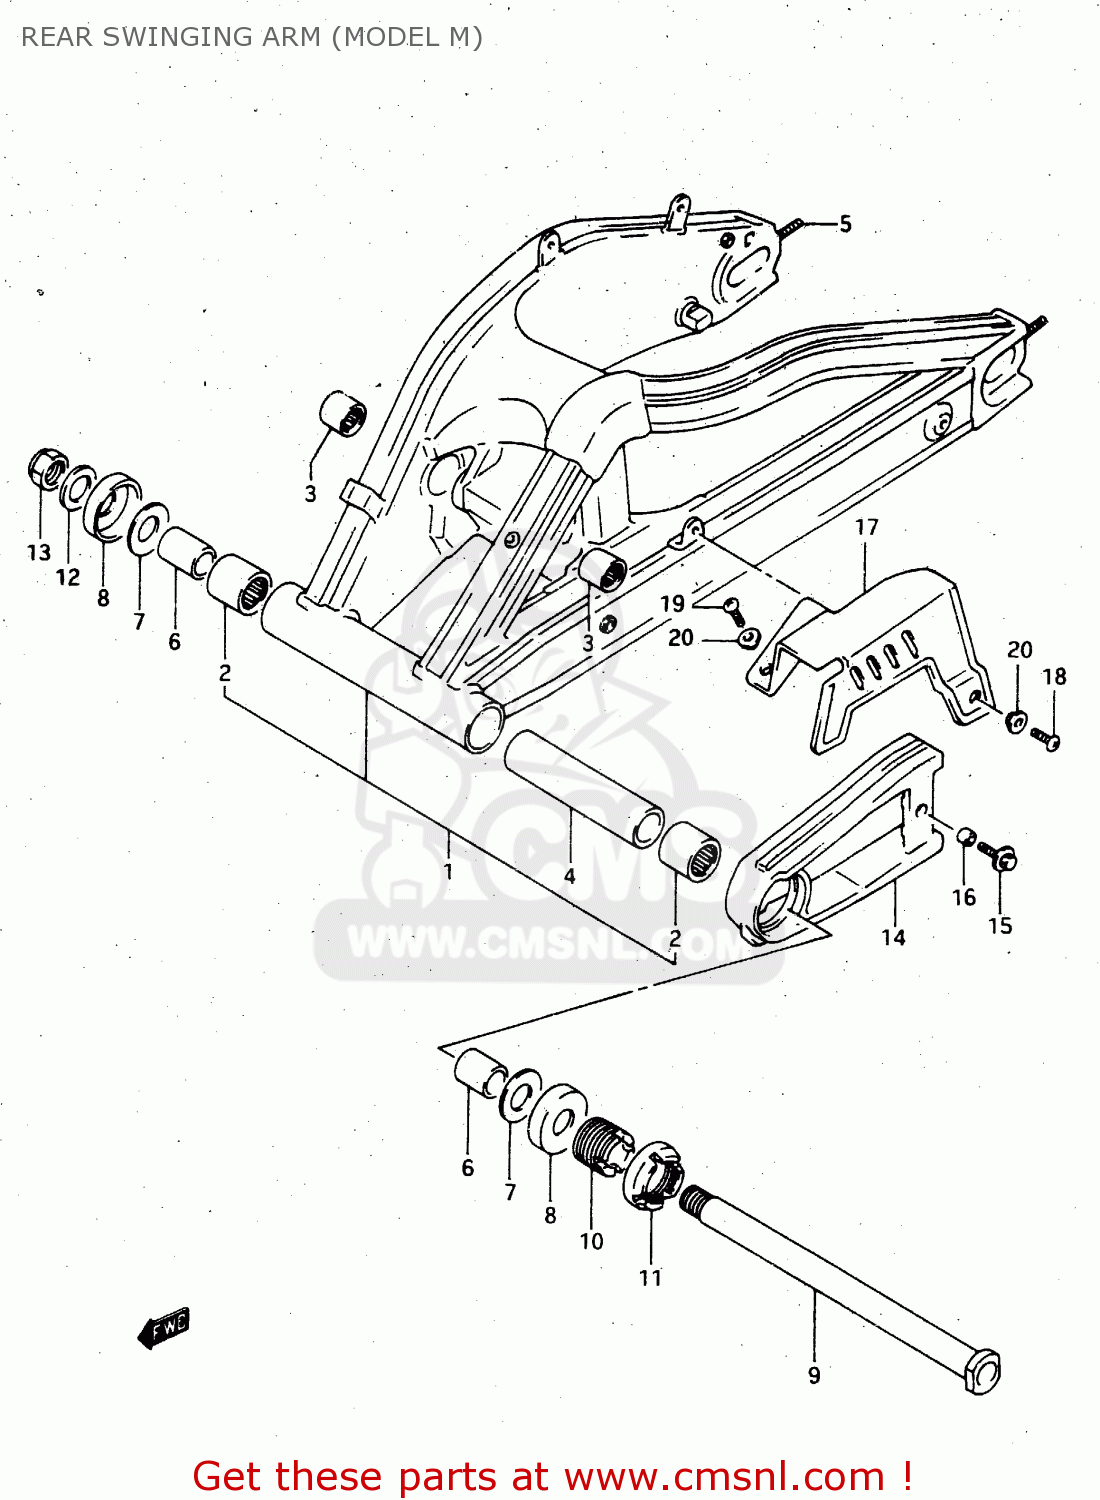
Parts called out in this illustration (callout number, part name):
1	SWINGING ARM ASSY, REAR
2	BEARING(25X33X30)
3	BEARING(17X24X20)
4	SPACER,RR SWGARM PIVOT CTR
5	STUD,CHAIN ADJUSTER BOLT
6	SPACER,RR SWGARM PIVOT BERRING
7	WASHER
8	DUST SEAL,RR SWGARM PIVOT
9	SHAFT,RR SWINGINGARM PIVOT
10	BOLT,RR SWGARM PIVOT
11	NUT,REAR SWING ARM PIVOT
12	WASHER
13	NUT
14	BUFFER,CHAIN TOUCH DEFENSE
15	BOLT 6X20,WITH PLAIN WASHER
16	SPACER
17	CASE,CHAIN
18	SCREW
19	SCREW, CENTER
20	WASHER
